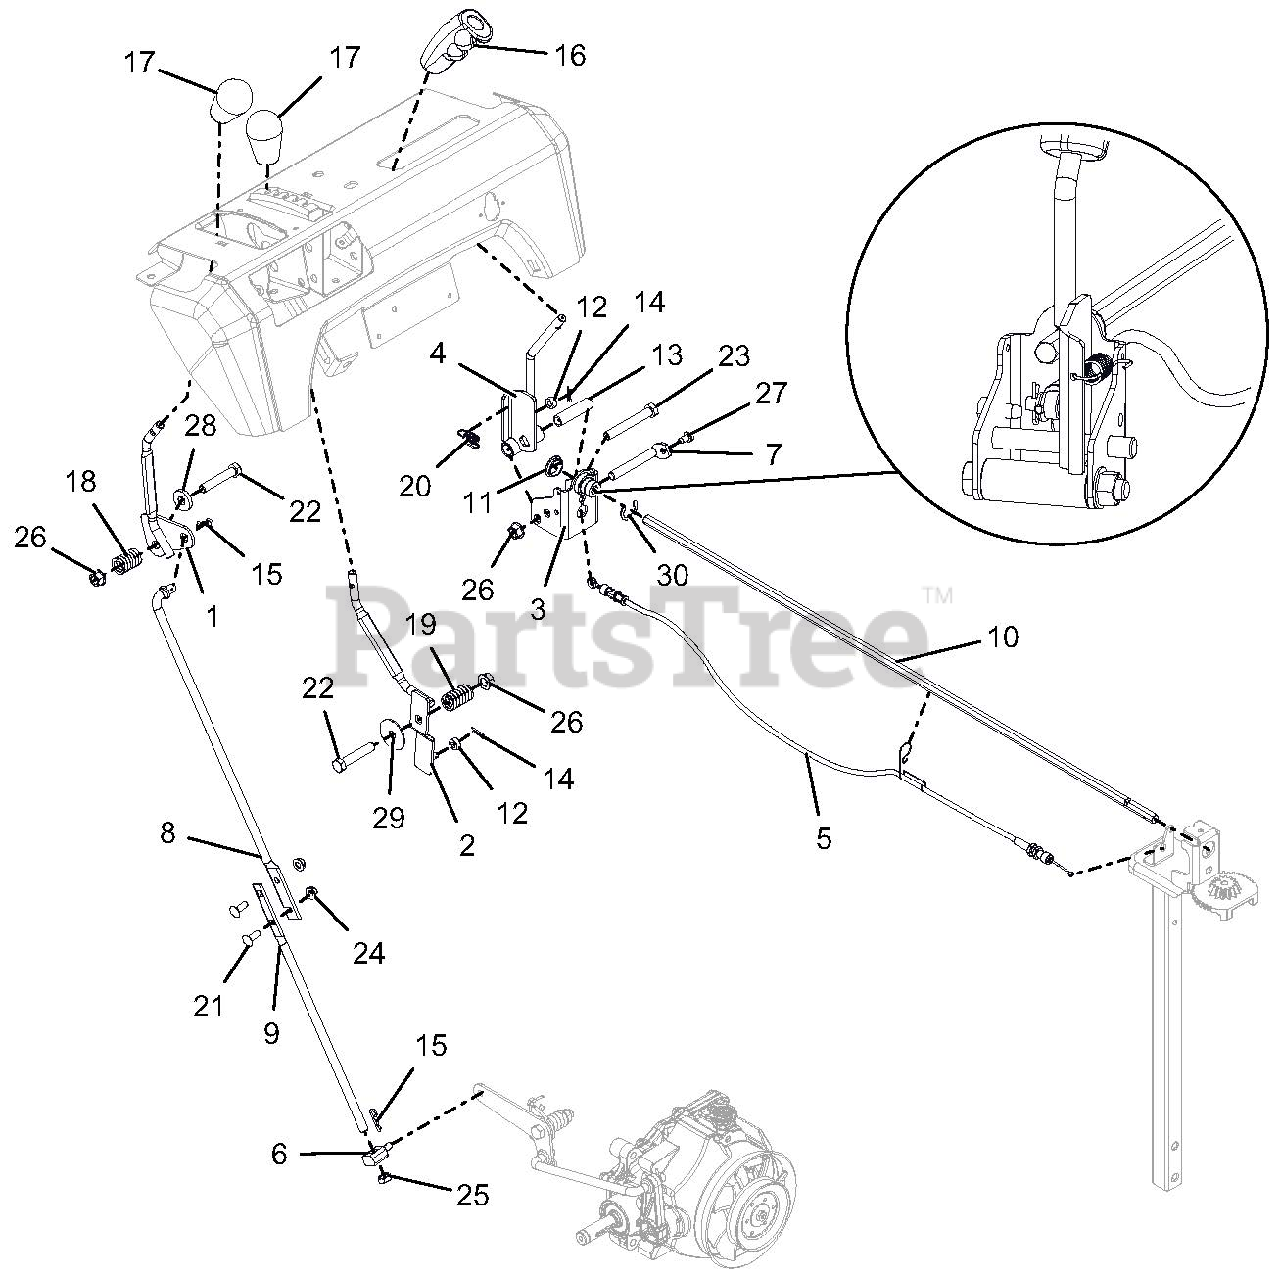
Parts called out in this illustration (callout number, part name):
1	WELDMENT, CONTROL LEVER(SHIFT)
2	WELDMENT, CONTROL LEVER (DEFL)
3	WELDMENT-CONTROL BRACKET-CHUTE
4	WELDMENT, CONTROL LEVER
5	CABLE, CHUTE LOCK, PRO
6	PIVOT,SHIFT ROD .375-16(TRUNN)
7	ROD, PIVOT - INTERLOCK
8	ROD, SHIFT - UPPER
9	ROD. HYDRO SHIFT - LOWER
10	ROD, HEX - CHUTE ROTATION
11	BUSHING, POLYLINER-.75 SNAPIN
12	BSHG-SLV .265X.500X.219
13	SPCR, WHEEL .385X.500X2.00
14	PIN-HAIR INT .06X.18X.77
15	PIN-HAIR INT .08X.18X1.18 YWZC
16	CONTROL HANDLE, QUICK TURN
17	KNOB,SOFT TEARDROP,PUSH-ON GRY
18	SG-COMP .125X.781X1.250
19	SG-COMP .125X.781X1.250
20	SPRING-EXT .047X.438X1.45
21	@BLT-RDHDSQNK .25-20X.75 G5YZ
22	@BLT-HEX .38-16X2.00 GR5 YWZC
23	@BLT-HEX .38-16X2.75 GR5 YWZC
24	@NUT-LK-CTR-FLG .25-20 YWZC
25	NUT-HEX-JAM .375-16 YWZC
26	@NUT-LK-TOP-FLG .38-16 YWZC
27	SCR-TAP .25-20X.50 HWH TR YWZ
28	WSHR-FL-STL .406X1.00X.188 YWZ
29	WSHR-FL-STL .380X1.50X.062 YWZ
30	E-RING .750X.050
